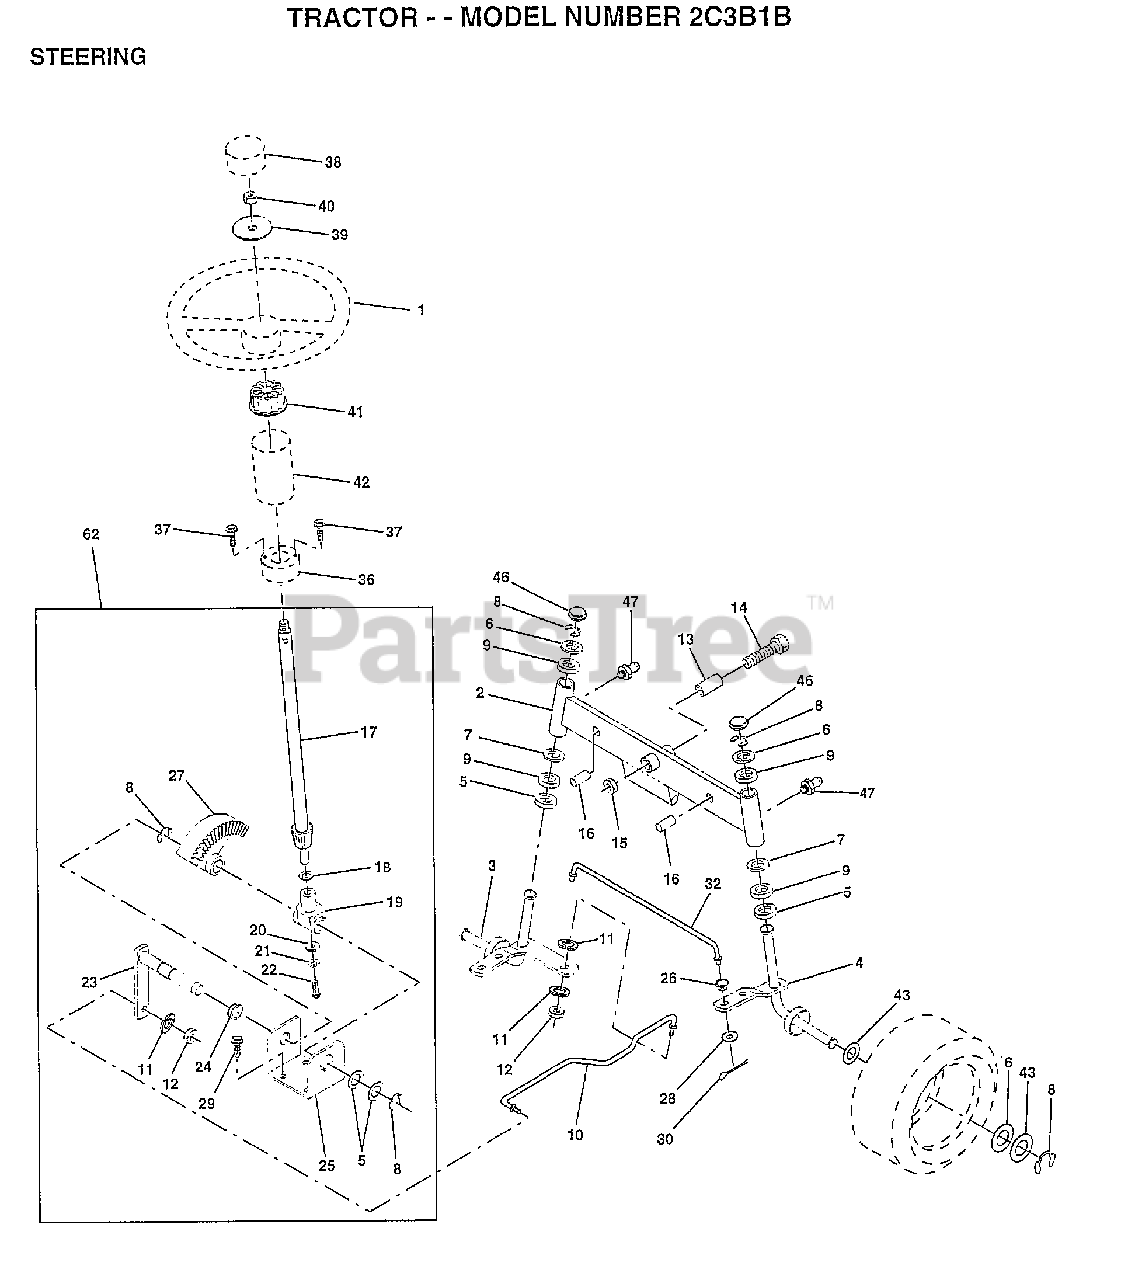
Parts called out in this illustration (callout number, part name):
2	AXLE ASM FRONT
3	SPINDLE LH
4	SPINDLE RH
5	WASHER .T
6	WASHER
7	WASHER
8	RING
9	COL. SRTG. BEAR.
11	LOCKWASHER
13	BEARING
14	BOLT HEX 5/8-11
15	"NUT-LOC,FLANGE LT"
16	AXLE PIN
17	SHAFT ASM
18	THRUST WASHER
19	SUPPORT.SHAFT
21	LOCKWASHER
22	SCREW.SCKTHD.CAP
24	NYLINER T
25	"BRKT,STEERING"
26	BUSHING.DRAGLINK
27	GEAR SECTOR
28	WASHER
29	SCREW
30	COTTER PIN
32	TIE ROD
38	ST WHL INSERT CAP
39	WASHER T
40	GRIPCO NUT
41	ADAPTER-WHEEL LT
42	"TUBE, STR SHAFT"
46	CAP
47	ZERK M
